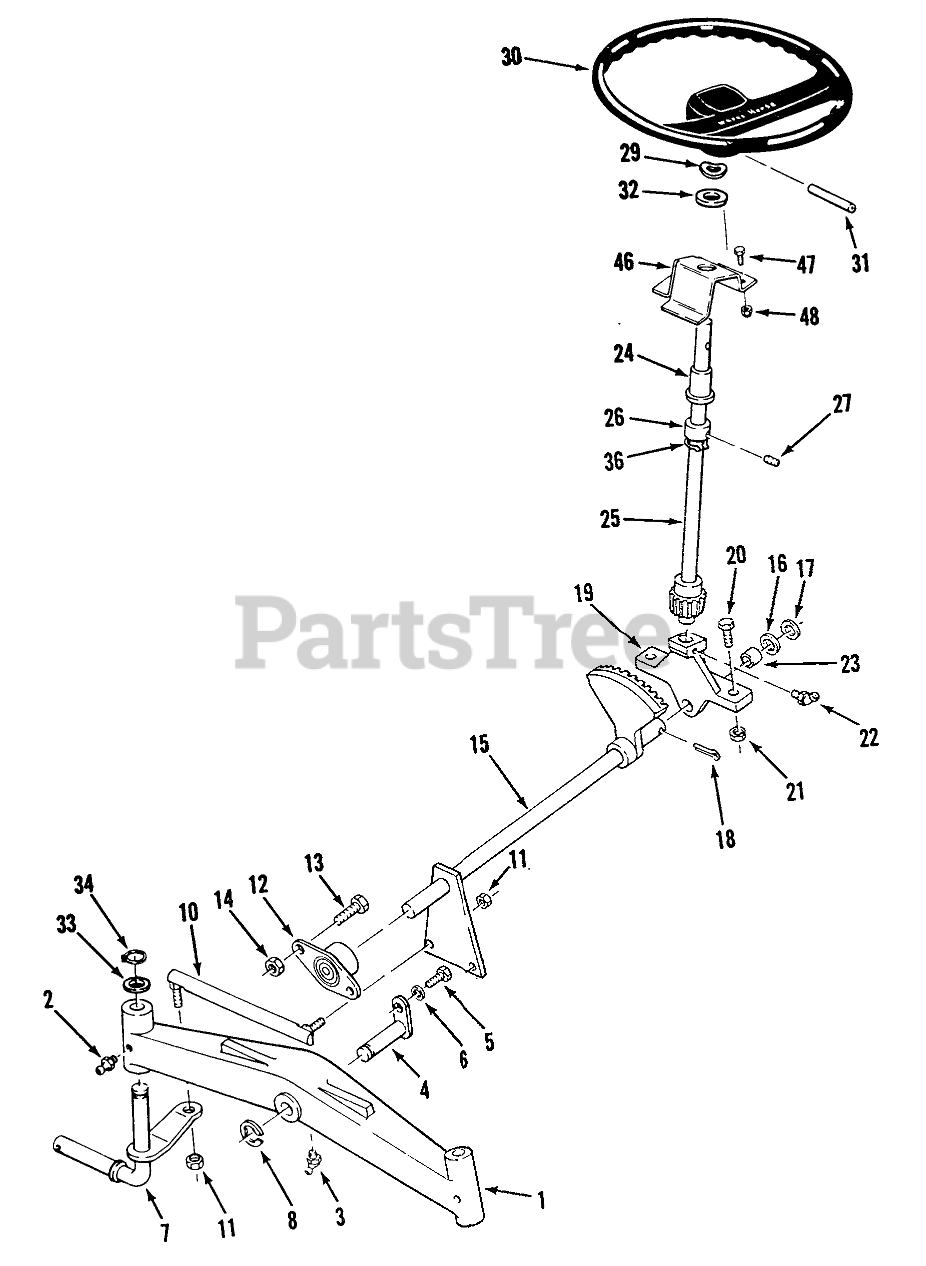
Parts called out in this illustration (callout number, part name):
1	AXLE-FRONT
2	Zerk
3	FITTING-GREASE
4	PIN AND PLATE ASM
5	H H C S
6	Lockwasher
7	RH SPINDLE WA
8	E-RING
10	Tie Rod RH
11	NUT-6
12	BEARING-FLANGED
13	Bolt
14	Nut
15	ASS'Y-STRG SHAFT R
16	WASHER-SHIM
17	WASHER
18	PIN-4
19	Support
20	BOLT
21	Nut
22	FITTING-GREASE
23	BEARING-BRONZE
24	BEARING-FLANGED
25	Shaft-Upper Steering
26	Collar
27	SCREW-SET
29	WASHER-BOWED
30	STEERING WHEEL-15"
31	Pin-Roll
32	WASHER-FLAT
33	WASHER
34	Snap Ring
36	RING-RETAINING
46	BRACKET-STEERING B
47	H H C S
48	Nut
